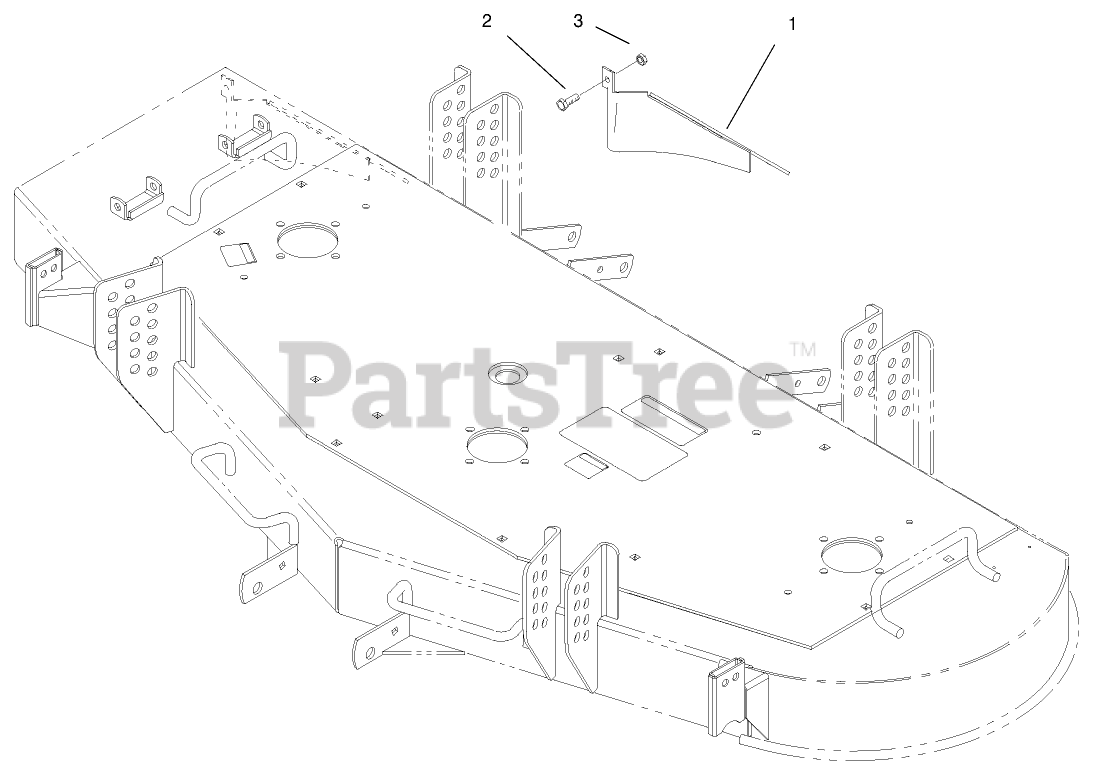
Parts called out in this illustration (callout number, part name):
1	REAR BAFFLE ASM, WELDED
2	SCREW-HH
3	NUT-HF
